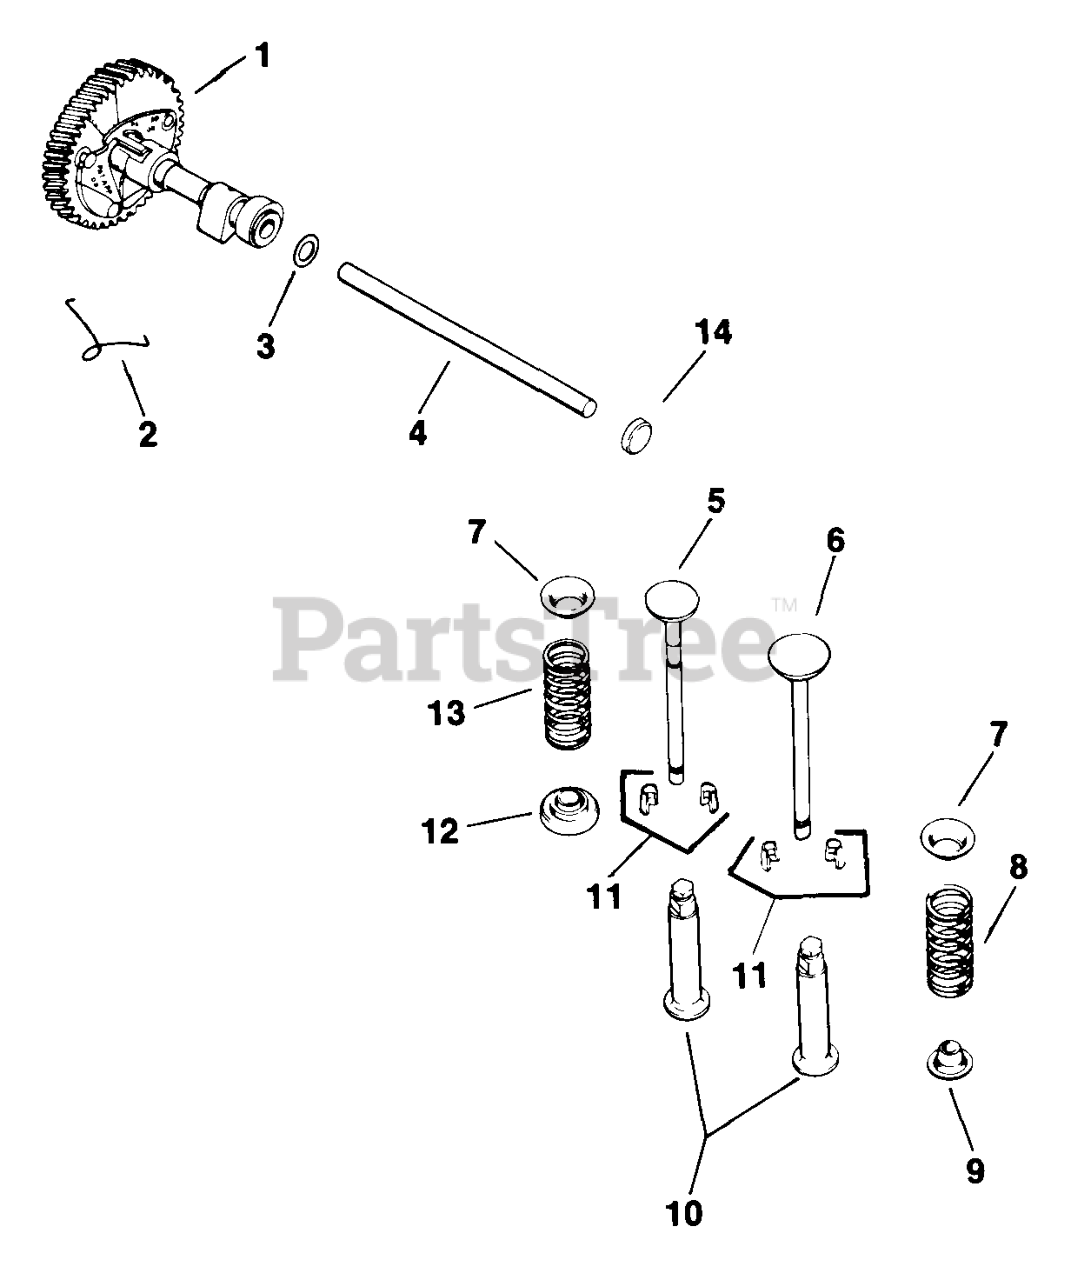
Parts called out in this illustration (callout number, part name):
1	CAMSHAFT ASSY - DISCONTINUED
2	SPRING, ACTUATING-DISCONTINUED
3	SPACER (.005")
3	SPACER (.010")
4	PIN, CAMSHAFT - DISCONTINUED
5	VALVE, EXHAUST
6	VALVE, INTAKE - DISCONTINUED
7	RETAINER, SPRING
8	SPRING, EXHAUST VALVE-(#DSC)
9	RETAINER, VALVE SPRING
11	KIT, RETAINER
12	ROTATOR - USE 52 413 01
13	SPRING, INTAKE VALVE - DISCONTINUED
14	PLUG, CUP 1/2" USE 25 139 50-S
